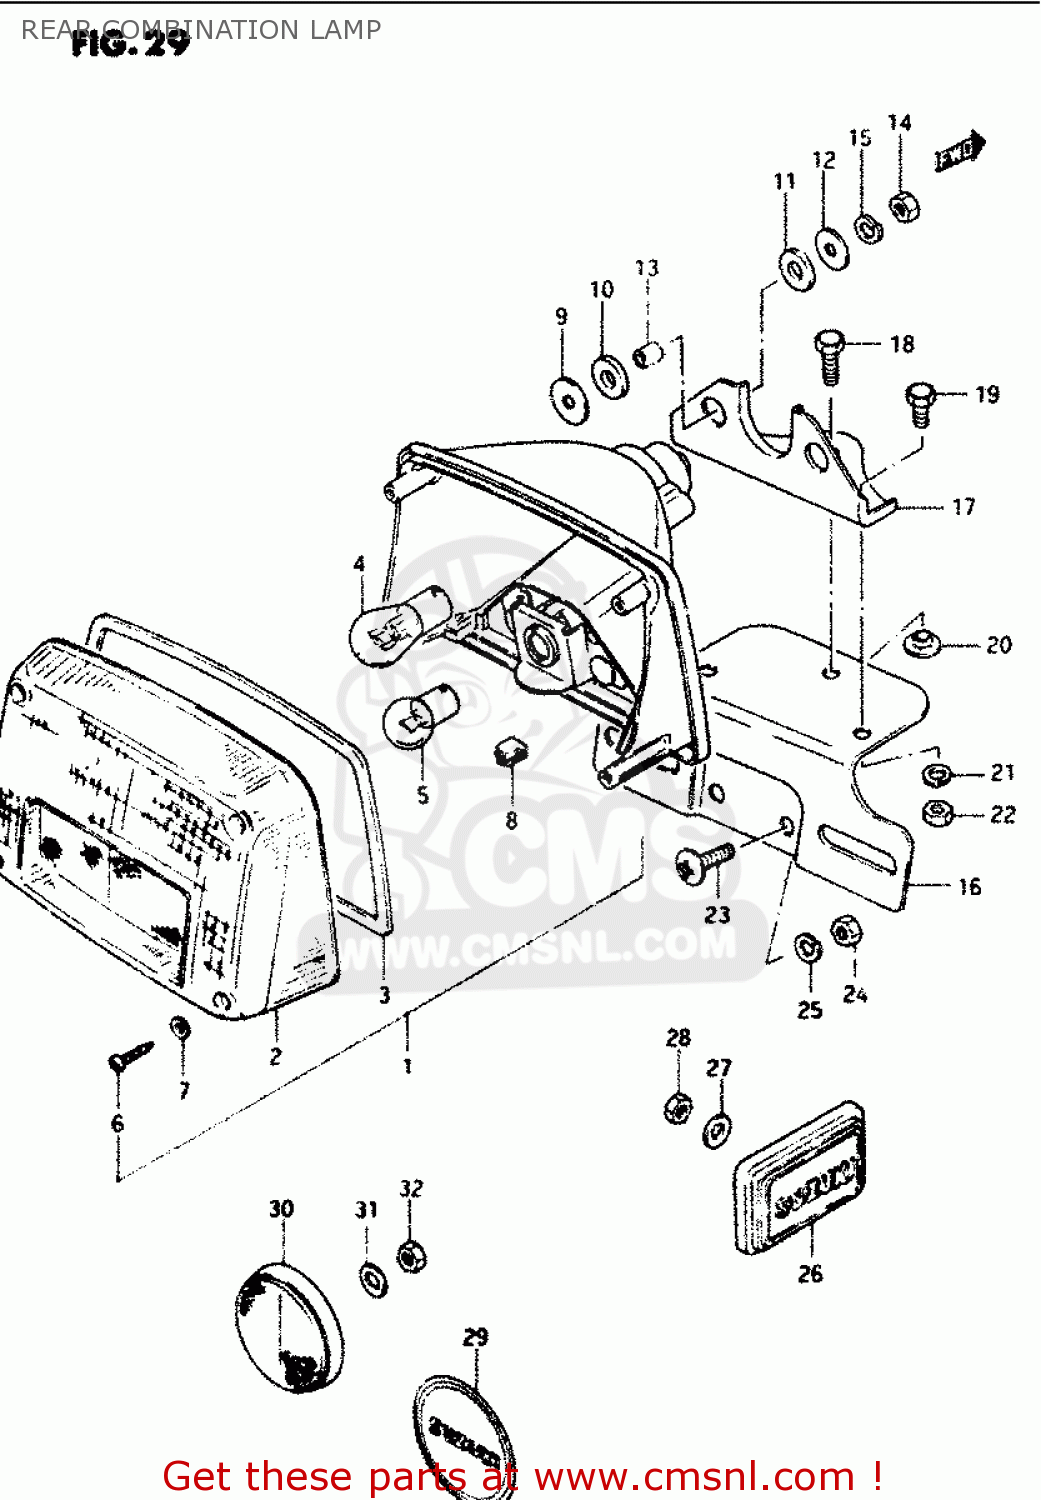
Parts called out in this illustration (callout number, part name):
1	LAMP ASSY, REAR COMBINATION
2	LENS
3	GASKET (NAS)
4	BULB(12V23W)
5	BULB
6	SCREW,REAR COMBINATION LAMP
7	GASKET (NAS)
8	GROMMET
9	WASHER
10	CUSHION
11	CUSHION
12	WASHER(6,5X22X1.6)
13	SPACER(6.1X9X7.5)
14	NUT
15	WASHER,LOCK
16	BRACKET, LICENCE PLATE
17	BRACKET,REAR COMBINATION LAMP
18	BOLT
19	BOLT
20	WASHER
21	WASHER,LOCK
22	NUT
23	SCREW
24	NUT
25	WASHER,LOCK
26	EMBLEM, REAR SIDE
27	WASHER
28	NUT
29	EMBLEM, REAR
30	REFLEX REFLECTOR,RR
31	WASHER
32	NUT
